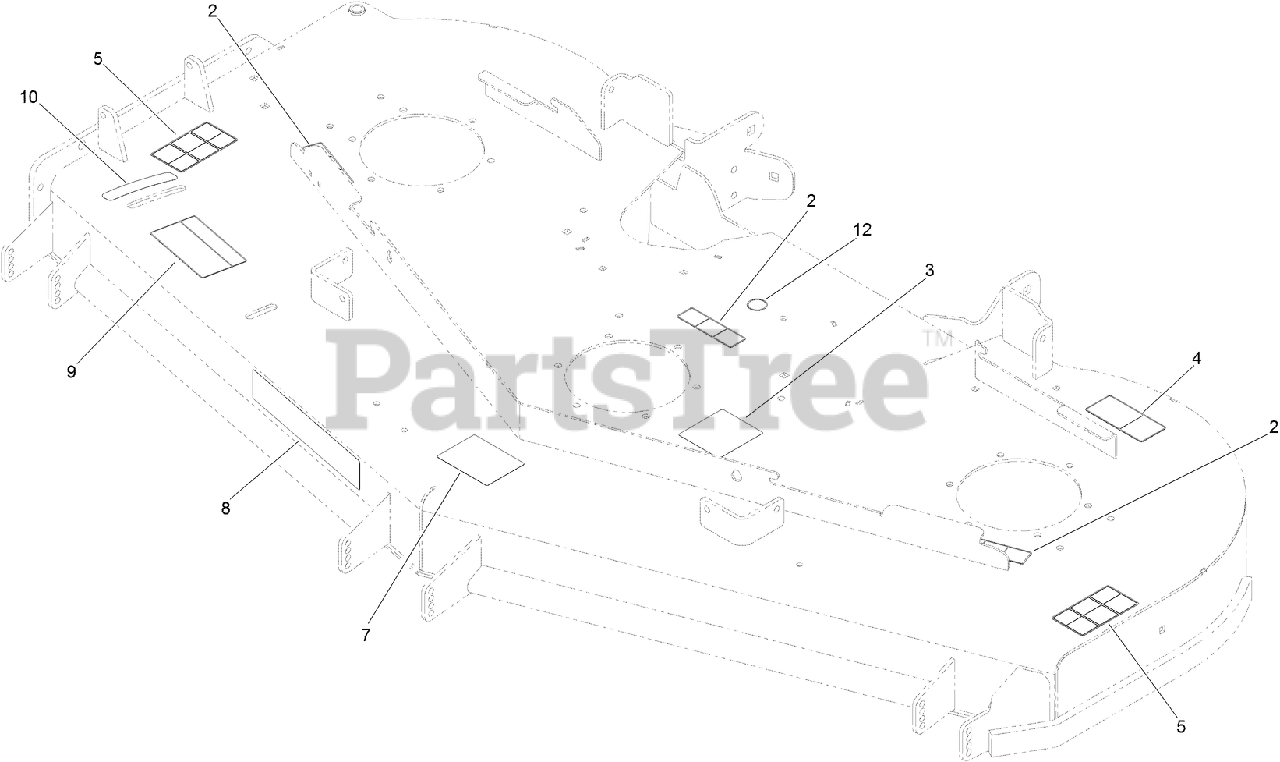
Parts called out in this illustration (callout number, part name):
2	DECAL-MISSING, COVER
3	DECAL-ROUTING, DECK BELT
4	DECAL-TORQUE, BLADE BOLT
5	DECAL-DANGER
7	DECAL-SCALP, ANTI
9	DECAL-ADJUSTMENT, BAFFLE
10	DECAL-SETTING, BAFFLE
12	DECAL-GREASE
